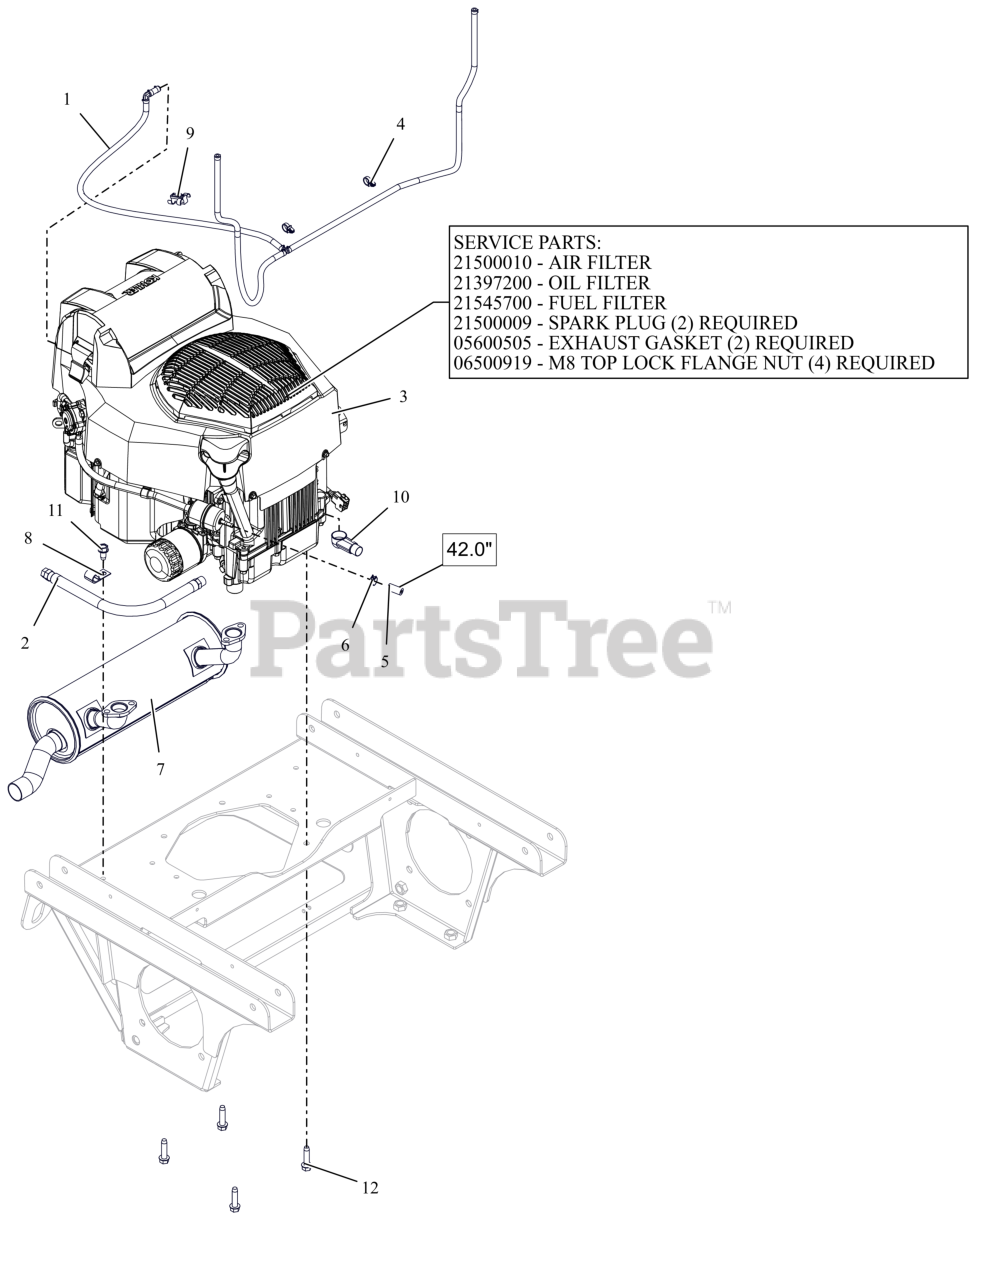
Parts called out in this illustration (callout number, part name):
1	ASM, VAPOR LINE
2	HOSE, OIL DRAIN
3	ENGINE, KOHLER ZT740 CONFIDANT
3	AIR CLEANER, KOHLER CONFIDANT
3	FILTER, OIL - KOH CV20
3	FILTER-FUEL KOHLER COURAGE PRO
3	PLUG, SPARK KOHLER
3	GASKET, MUFFLER KOHLER TWIN
3	NUT-LK-TOP-FLG M8 ZCC
4	ROUTING CLIP (1/2" ID)
5	HOSE, .25 LOW-PERM BULK GAS
6	CLAMP, FUEL LINE
7	MUFFLER, ZT730/ZT740
9	CLIP, T, .38-.50
10	BOOT, .65ID POS
11	SCR,TAP .375-16X.75 HWH TR ZCC
12	SCR-TAP .38-16X1.50 HWH ZCC
